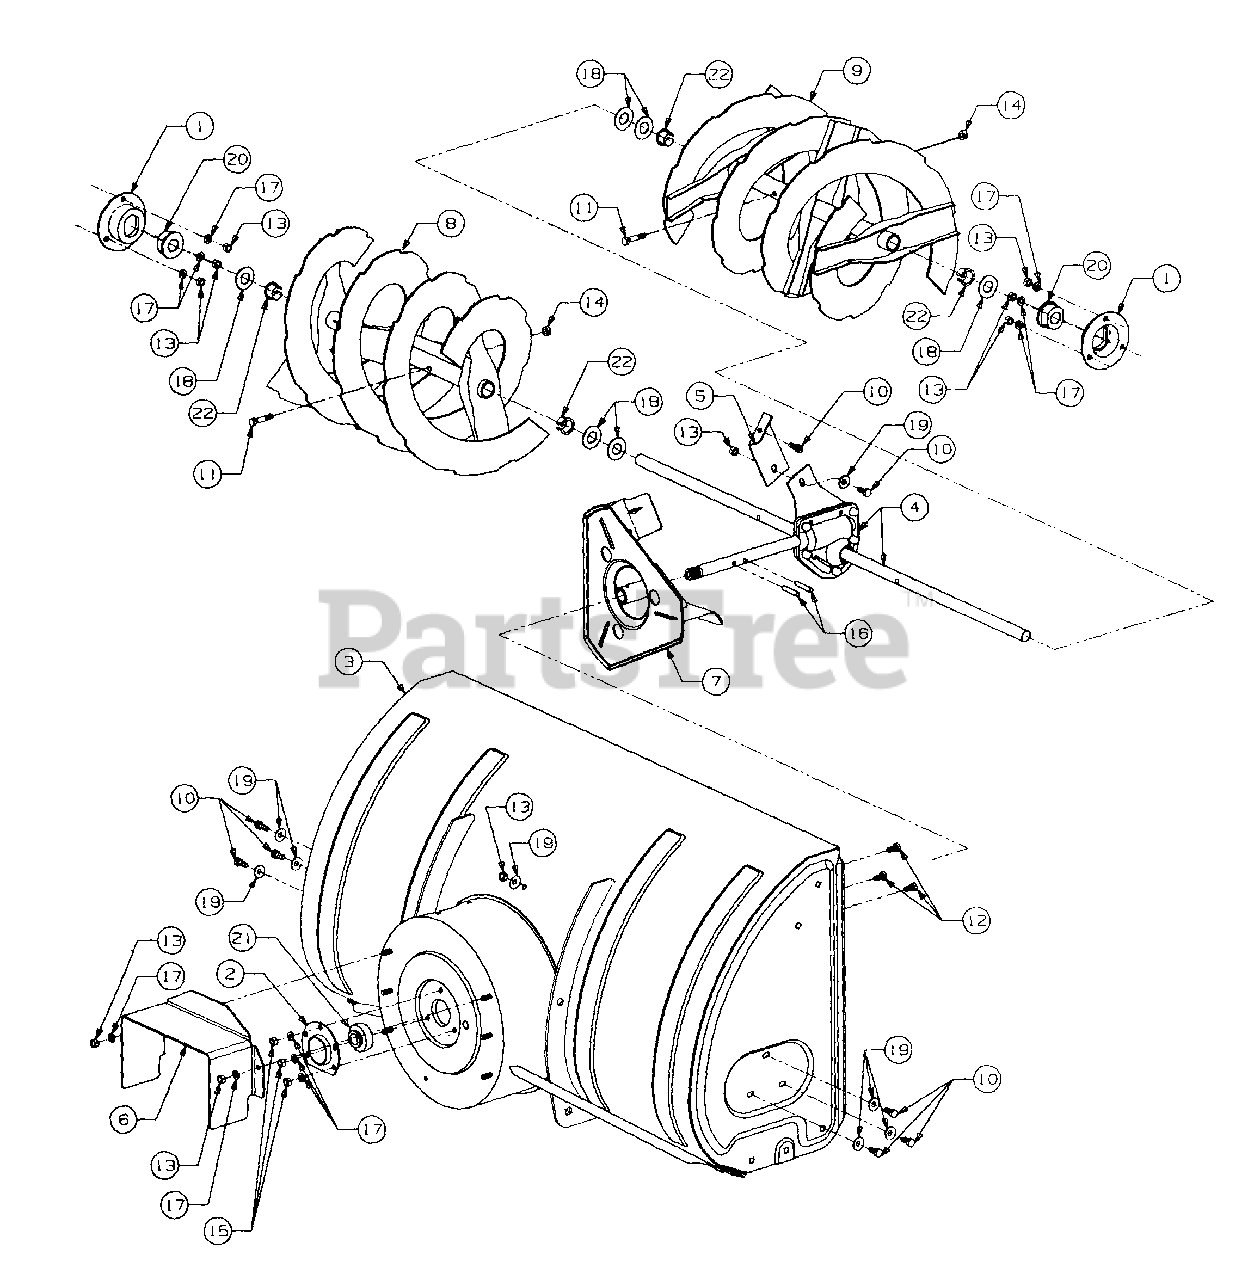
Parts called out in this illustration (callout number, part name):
2	Housing, Bearing
4	Gear Assy, Auger
11	Bolt, Shear, 5/16-18 X 1.50 Lg
12	Screw, Hex Cap, 5/1 6-18 X .625 Lg GR2
13	Nut, Hex, 5/16-24
14	Nut, Hex Center Lock, 5/16-18
15	Nut, Hex, 5/16-18
16	Pin, Spiral Spring, 1/4 Dia X 1.50 Lg
17	Washer, Lock, 5/16
18	Washer, Flat, .76 X 1.49 X .06 Thk
19	Washer, Bell, .345 X .88 X .06 Thk
20	Bearing, Plastic Flange
21	Bearing
22	Bushing, Flange
